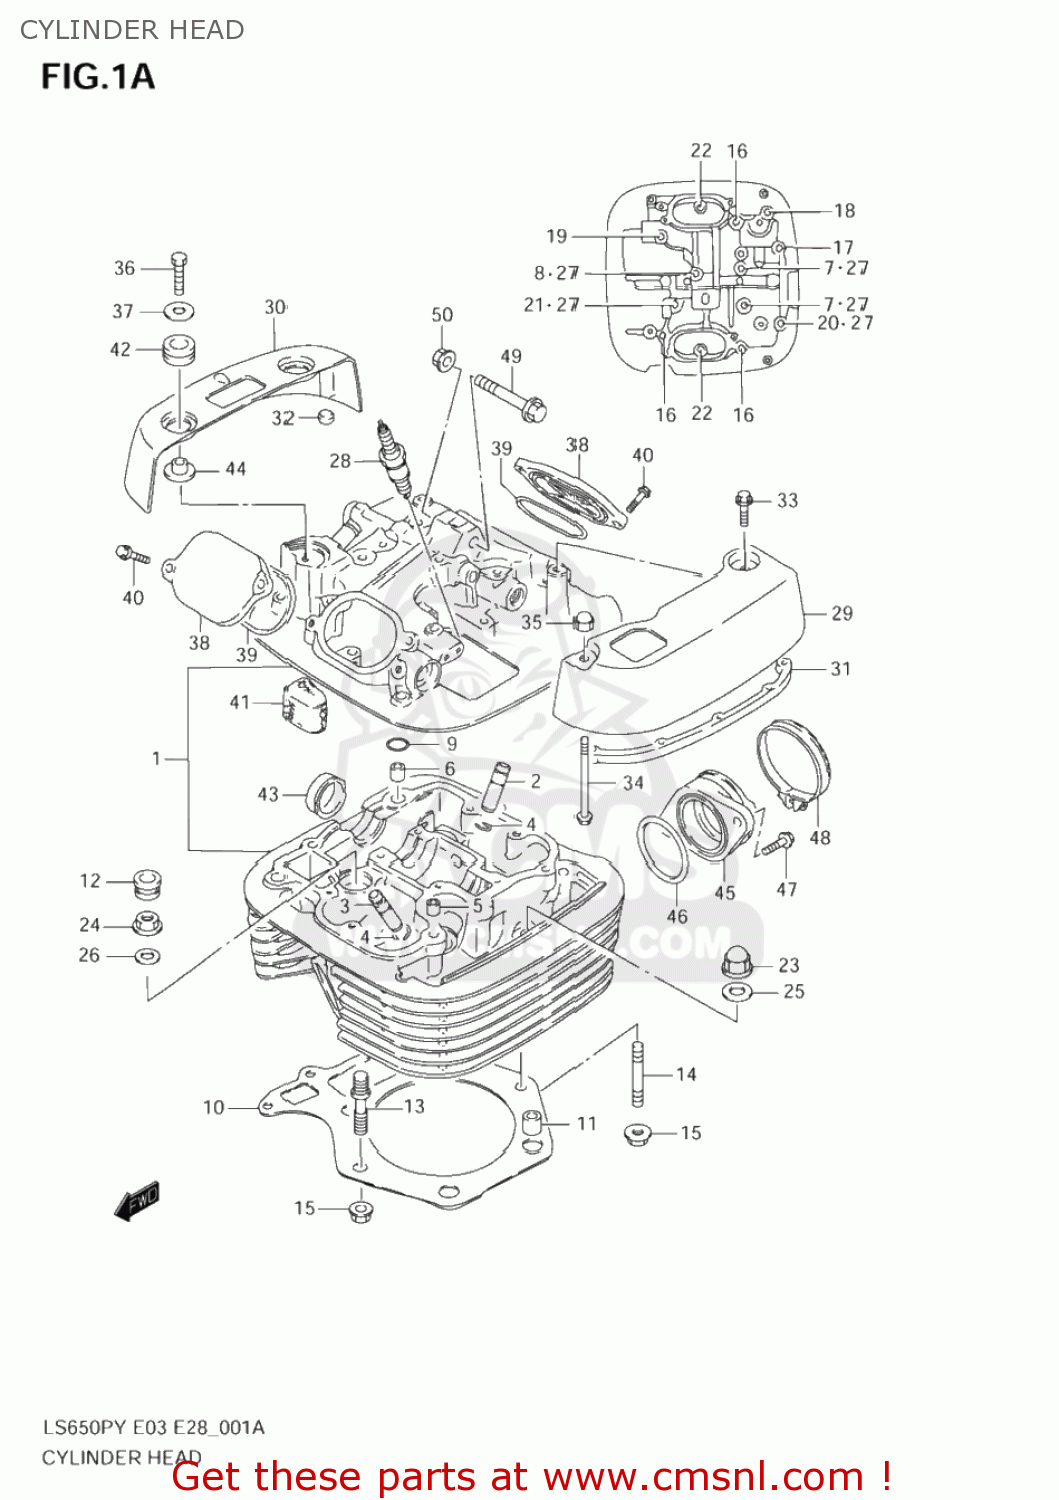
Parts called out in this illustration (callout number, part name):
1	HEAD ASSY,CYLINDER
2	GUIDE,VALVE
3	GUIDE,VALVE
4	RING,SNAP
5	PIN(6.2X8X11)
6	PIN(11X14)
7	BOLT(6X60)
8	BOLT(6X70)
9	O RING,CYL HEAD COVER
10	GASKET,CYLINDER HEAD (NAS)
11	PIN
12	CAP,CYLINDER HEAD SEAL
13	BOLT,STUD
14	BOLT,STUD(8X31)
15	NUT
16	BOLT(6X39)
17	BOLT(6X125)
18	BOLT(6X115)
19	BOLT(6X60)
20	BOLT(6X130)
21	BOLT(6X55)
22	BOLT
23	NUT
24	NUT
25	GASKET(10.2X20X2).3 (NAS)
26	GASKET(10.2X20X2).3 (NAS)
27	GASKET(5.8X13X1.2) (NAS)
28	SPARK PLUG X22E
29	CAP,HEAD COVER,L
30	CAP,CYLINDER HEAD COVER,R
31	CUSHION,HEAD COVER CAP,L
32	CUSHION,R CAP
33	BOLT
34	BOLT
35	NUT
36	BOLT
37	WASHER(6.5X24X1.6)
38	CAP,INSPECTION
39	O RING(D:2.4,ID:23)
40	BOLT
41	SEPARATOR,OIL BREATHER COVER
42	CUSHION
43	PLUG(OD:30)
44	BUSH
45	PIPE ASSY,INTAKE
46	O RING(D:2.4,ID:45.7)
47	SCREW
48	CLAMP
49	BOLT
50	NUT
